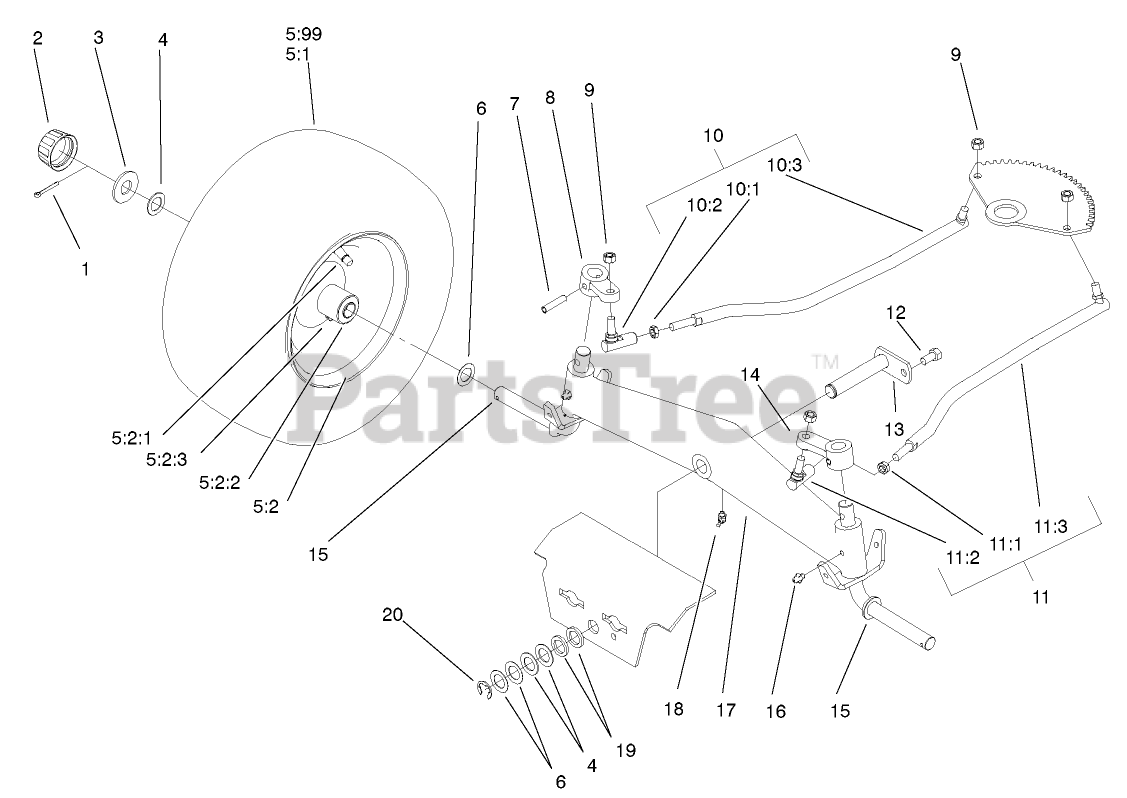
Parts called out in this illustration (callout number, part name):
1	PIN-COTTER
2	CAP-HUB
3	WASHER-PLAIN
4	WASHER
5	Front Wheel Tire ASM
5:2	WHEEL ASM
5:2:1	VALVE
5:2:2	BEARING-WHEEL
5:2:3	ZERK-GREASE
6	WASHER-SHIM
10	LINKAGE-STEERING, RH
11	LINKAGE-STEERING, LH
12	SCREW-HWH, TAPTITE
13	PIN-AXLE
16	FITTING-GREASE
17	AXLE ASM-FRONT
18	FITTING-LUBE, 45 DEG
19	WASHER
20	E-RING
